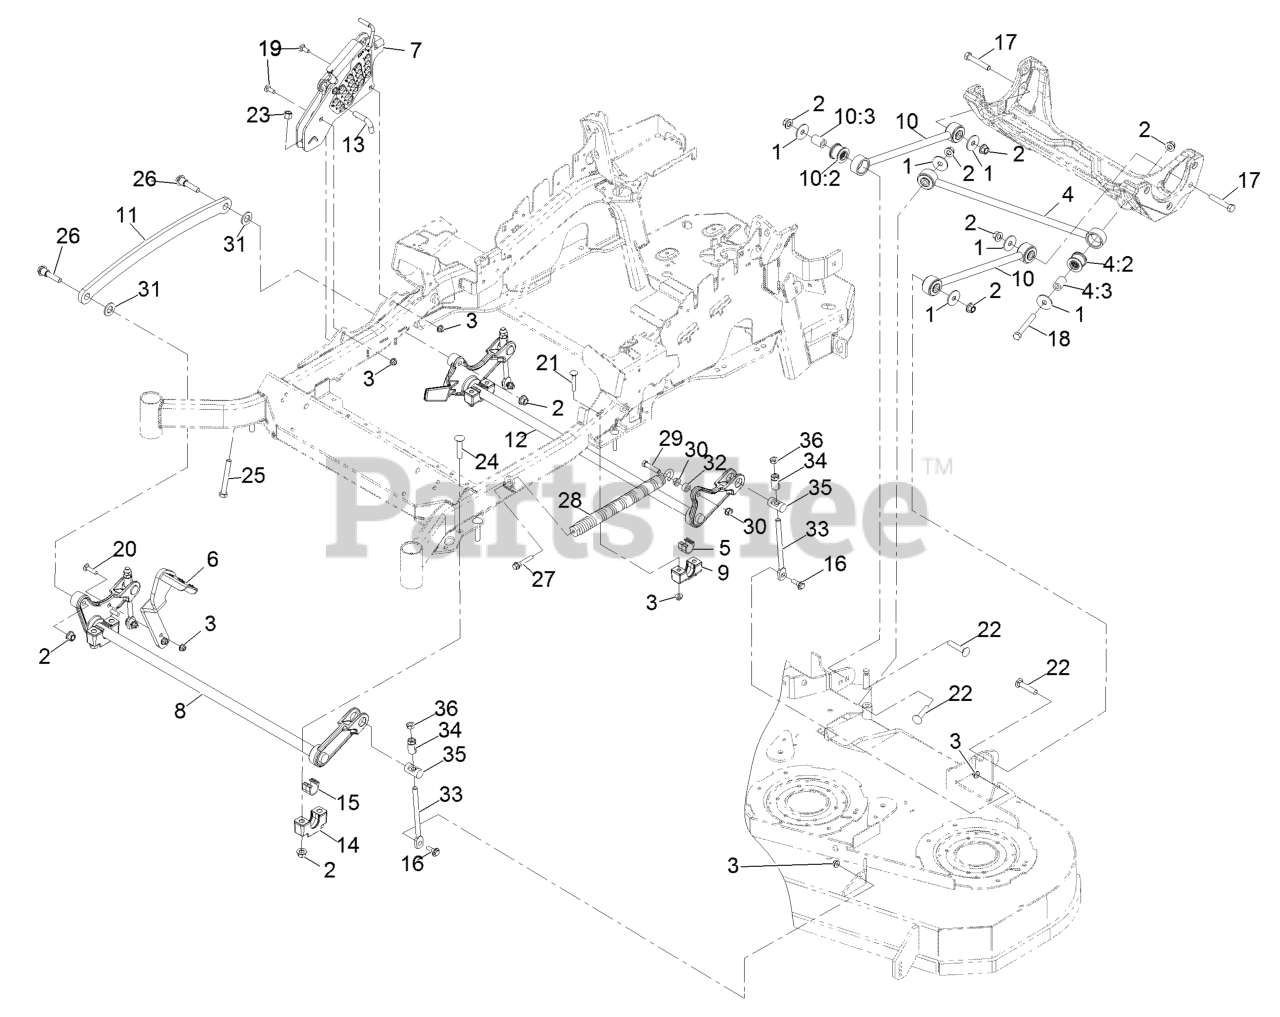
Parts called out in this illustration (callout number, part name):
1	WASHER-THRUST
2	Nut-Lock 1/2-13
3	NUT-HF, NI
4	PANHARD ROD ASM
4:2	BUSHING-SUSPENSION, RUBBER
5	BEARING-CROSS SHAFT, REAR
6	LEVER-FOOT
7	HOC ASM
8	DECKLIFT-FRONT
9	SUPPORT-CROSS SHAFT, BEARING REAR
10	DECK STRUT ASM
10:2	BUSHING-SUSPENSION, RUBBER
11	LINK-LIFT, DECK
12	LIFT-DECK, REAR
13	PIN-HOC
14	SUPPORT-CROSS SHAFT, BEARING
15	BEARING-CROSS SHAFT, FRON
16	SCREW-SHOULDER, HHF
17	SCREW-HH
18	SCREW-HH
19	BOLT-CARR
20	SCREW-CARR
21	Bolt-Carriage 3/8-16 X 2 1/4
22	SCREW-CARR
23	NUT-LOCK, NI
24	Bolt-Carriage 1/2-13 X 2 1/2 Spl Neck
25	BOLT-TAP
26	SCREW-HHF, SHOULDER
27	BOLT-SHOULDER
28	SPRING-EXTENSION
29	SCREW-HH
31	WASHER-FLAT
33	LINK-ADJUSTER, DECK LIFT
34	ADJUSTER-LIFT, DECK
35	TRUNNION
36	NUT-JAM
